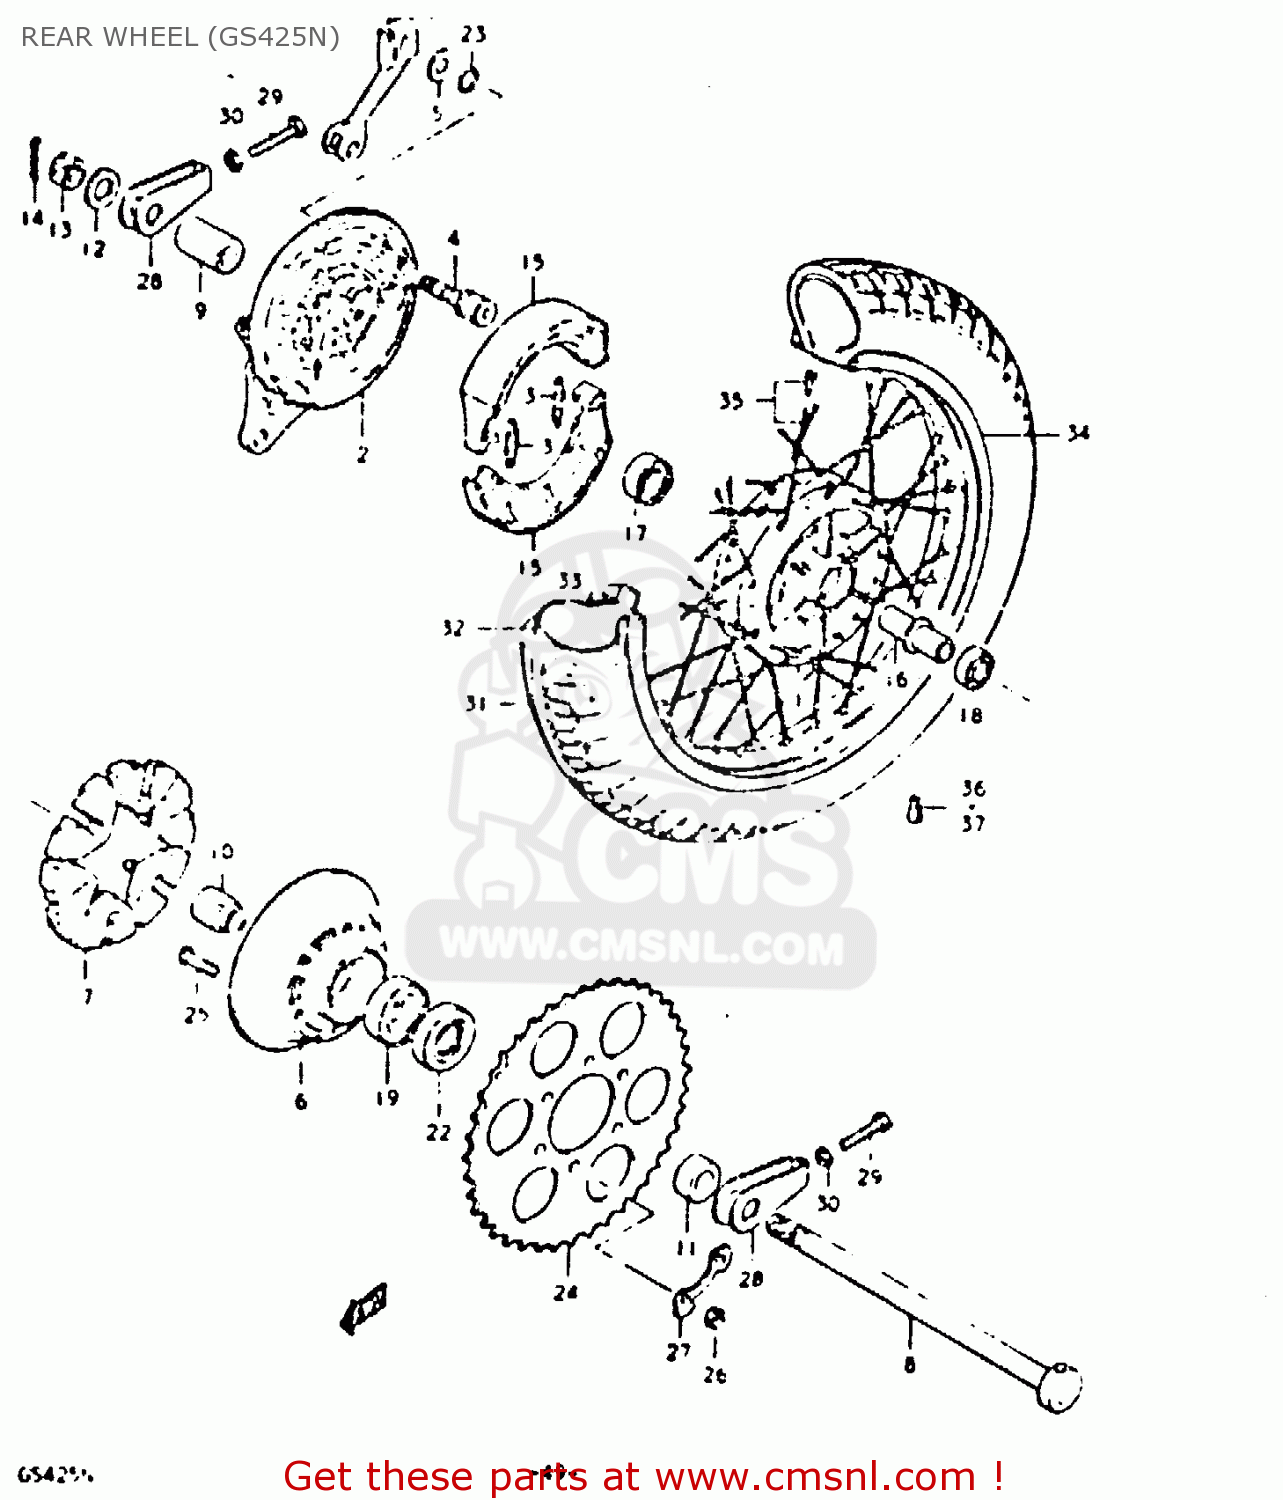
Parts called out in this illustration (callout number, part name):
1	DRUM,REAR HUB
2	PANEL,REAR HUB
3	SPRING,BRAKE SHOE
4	CAM,FRONT BRAKE
5	WASHER (15X24X1.6)
6	DRUM,REAR SPROCKET MOUNT
7	CUSHION,REAR DRUM
8	AXLE,REAR
9	SPACER(17.5X28X44.8)
10	SPACER,REAR HUB BEARING
11	SPACER(17X30.5X22.3)
12	WASHER (17X30X3.2)
13	NUT
14	PIN,COTTER
15	SHOE SET,BRAKE (MCA)
16	SPACER
17	BEARING
18	BEARING
19	BEARING
20	LEVER,REAR BRAKE CAM
21	BOLT
22	OIL SEAL
23	O-RING,BOSS
24	SPROCKET,RR
25	BOLT
26	NUT
27	WASHER
28	ADJUSTER,CHAIN
29	BOLT
30	NUT
31	TIRE
32	TUBE ASSEMBLY,WHEEL,INNER
33	PROTECTOR,INNER TUBE
34	RIM,RR WHEEL
35	SPOKE SET,REAR WHEEL
36	BALANCER,WHEEL (B)
37	BALANCER,WHEEL (30G)
